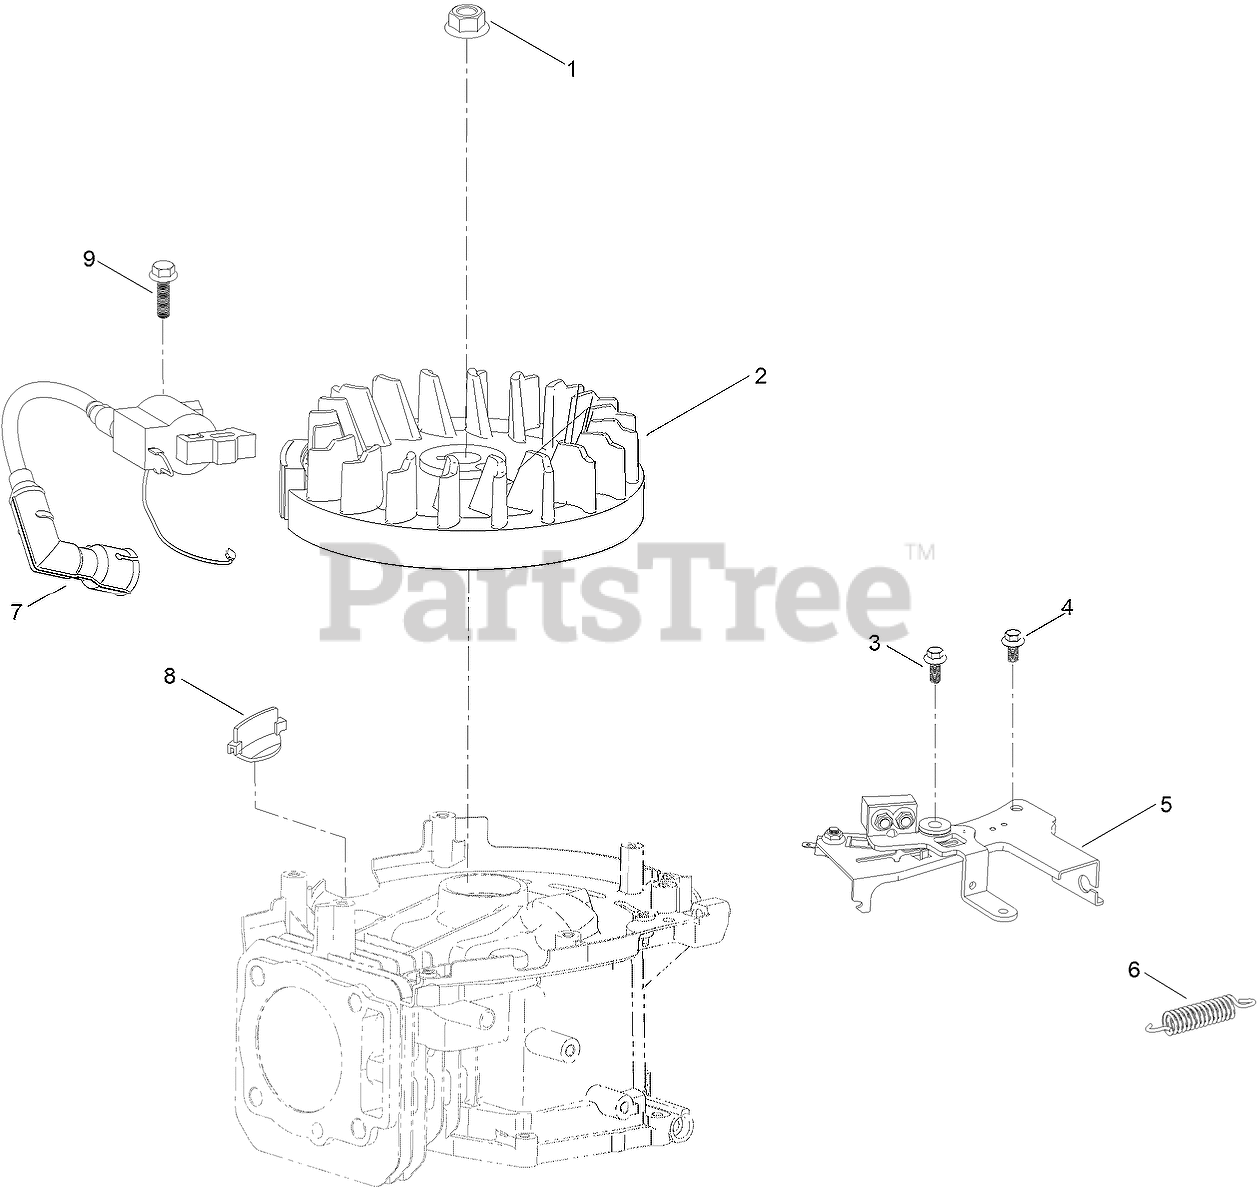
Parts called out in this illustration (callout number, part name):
1	NUT-FLANGE
2	FLYWHEEL
3	BOLT-FLANGE
4	SCREW-HHF
5	BRAKE ASM
6	SPRING-BRAKE
7	IGNITION COIL ASM
8	GUARD-FLYWHEEL
9	SCREW-HHF
